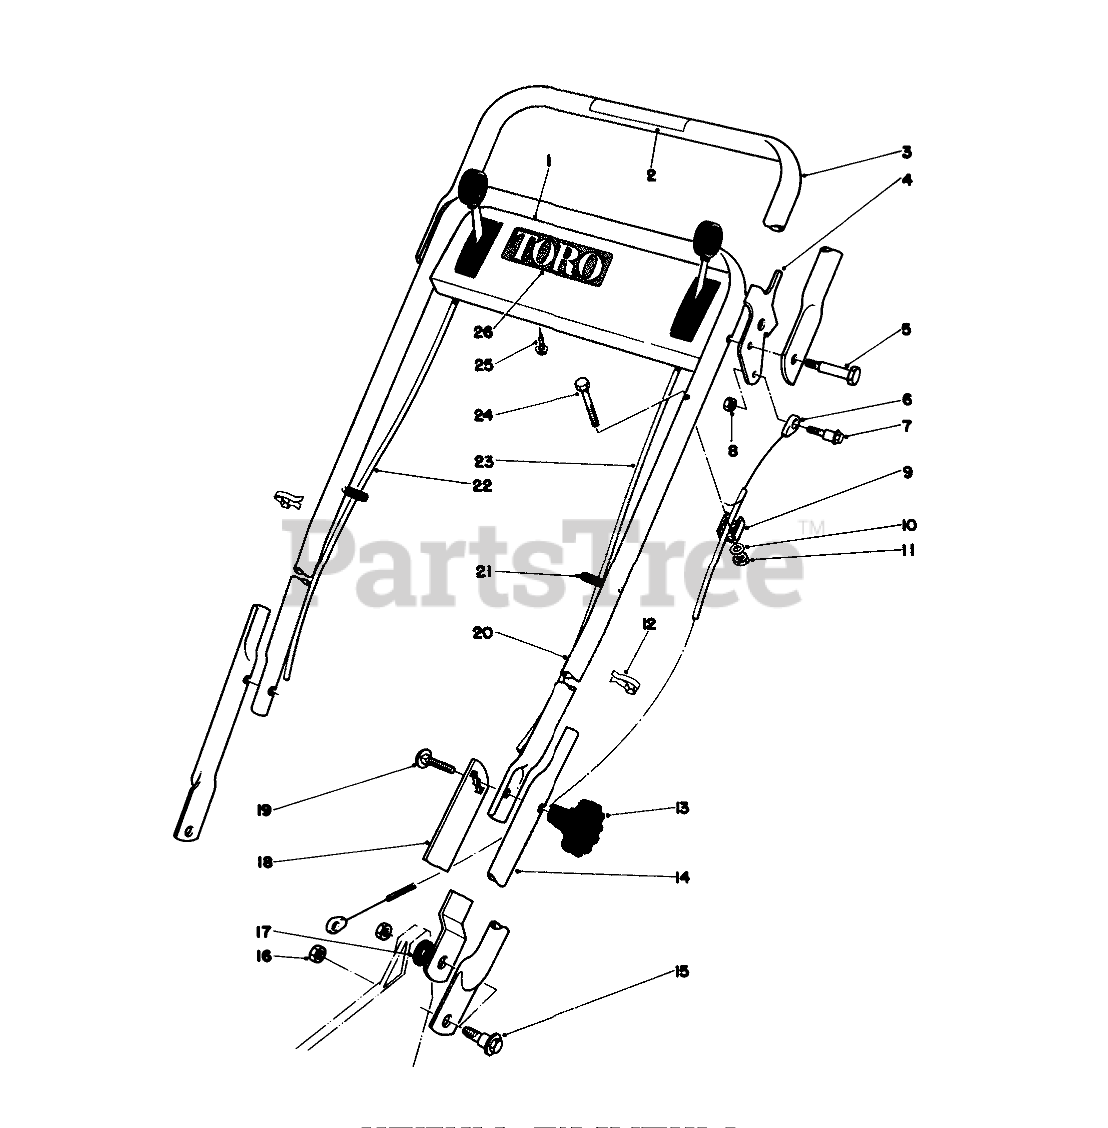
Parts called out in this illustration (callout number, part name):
1	Control Panel
2	Danger-Decal
3	Demand Handle
4	Demand Handle Stop
5	BOLT-SHOULDER
6	DEMAND HANDLE CABLE
7	Shoulder Bolt
8	NUT-HEX, SIDE DEFORM
9	CLAMP-CABLE
10	WASHER-FLAT
11	NUT-LOCK, NI
12	BOWDEN CLIP
14	LOWER HANDLE
15	SCREW-SHOULDER
16	Nut
17	SPACER
18	Handle Latch L.H.
19	SCREW-CARR
20	Upper Handle
21	CAP-VINYL
22	Ground Speed Control
23	Throttle Control
24	SCREW-HH
25	SCREW-HWHTF
26	Decal-Toro
